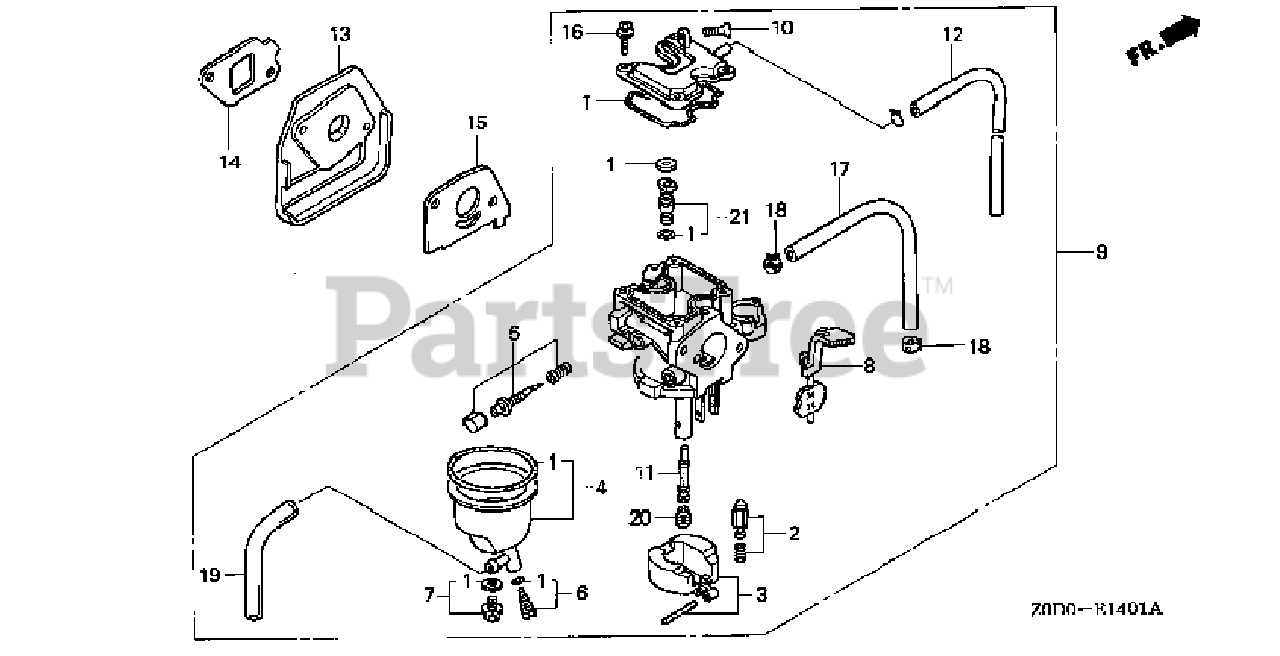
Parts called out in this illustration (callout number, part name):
1	GASKET SET
2	VALVE SET, FLOAT
3	FLOAT SET
4	CHAMBER SET, FLOAT
5	SCREW SET
6	SCREW SET, DRAIN
7	SCREW SET
8	LEVER SET, CHOKE
9	CARBURETOR ASSY. (BF33D A)
10	SCREW, THROTTLE STOP
11	NOZZLE, MAIN
12	TUBE, AIR VENT
13	INSULATOR, CARBURETOR
14	GASKET, INSULATOR
15	GASKET, CARBURETOR
16	SCREW-WASHER (4X12)
17	BULK HOSE, FUEL (4.5X3000) (4.5X270)
18	CLIP, TUBE (D8.5)
19	BULK HOSE, VINYL (3.5X6.5X8000) (3.5X6.5X100)
20	JET, MAIN (#60)
21	JET SET, PILOT (#35)
